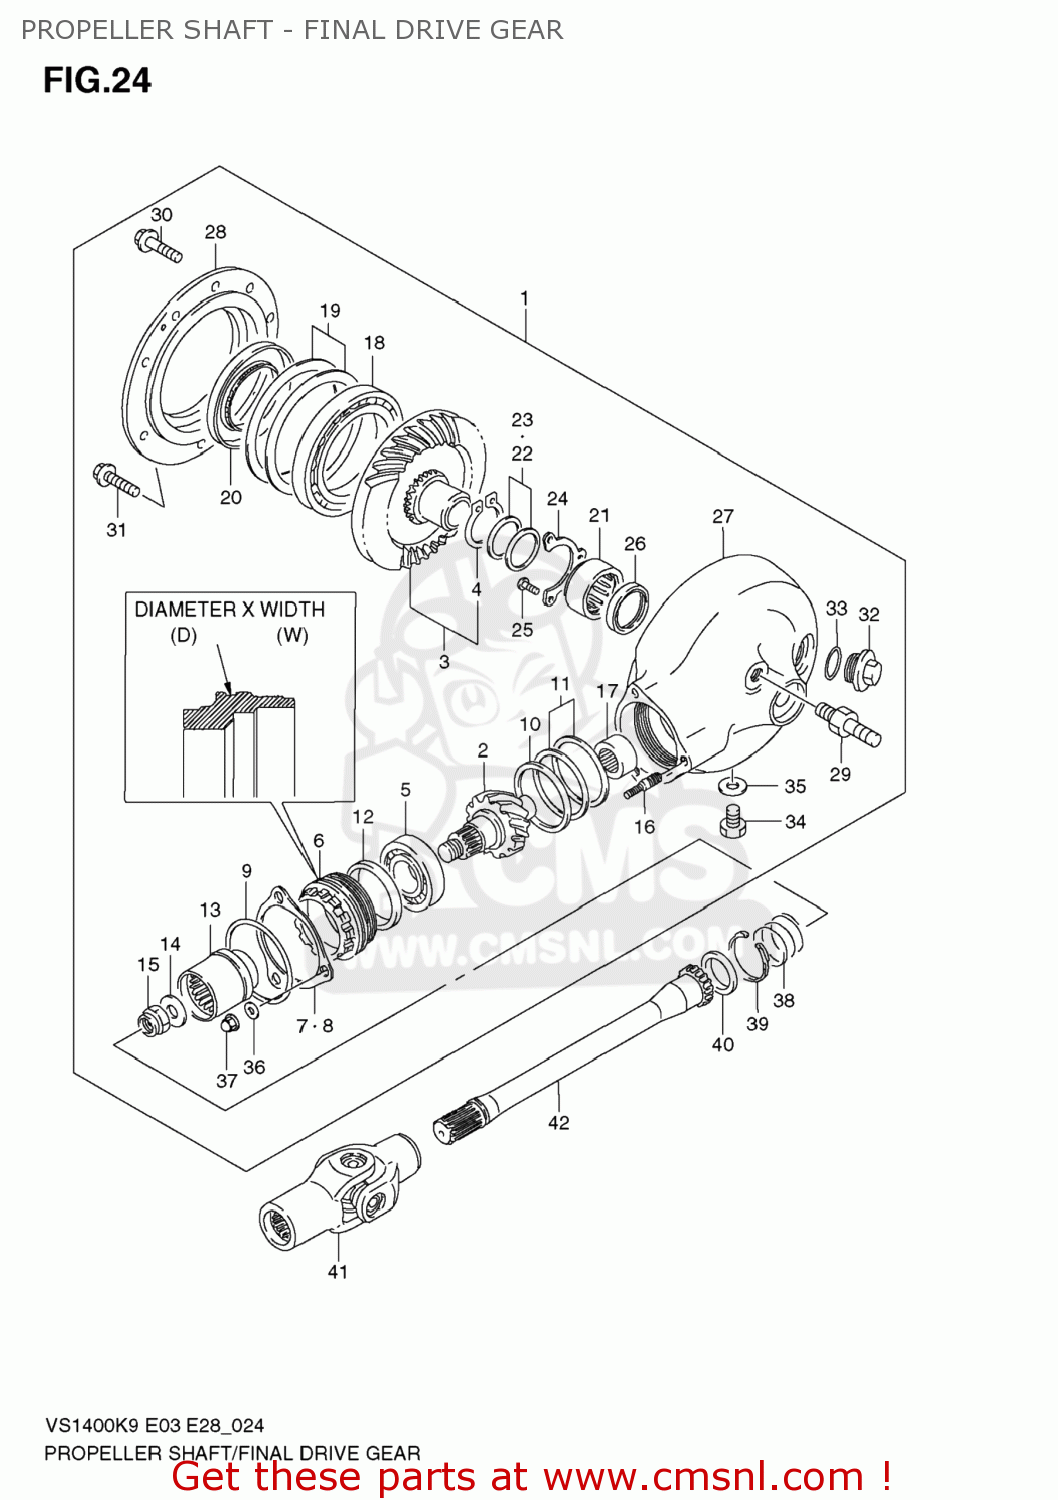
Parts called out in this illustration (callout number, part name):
1	GEAR & CASE SET,FINAL BEVEL
2	GEAR,FINAL DRIVE BEVEL
3	GEAR,FINAL DRIVEN BEVEL
4	.CIRCLIP
5	BEARING(28X68X18)
6	STOPPER,FINAL DRIVE BEARING
7	PLATE,BEARING STOPPER
8	PLATE,BEARING STOPPER
9	O RING(D:3.1,ID:63.9)
10	WASHER(54X68X1.5)
11	SHIM SET,FINAL DRIVE GEAR
12	SEAL,OIL
13	COUPLING,FINAL DRIVE GEAR
14	WASHER(16X29X4)
15	NUT
16	BOLT,STUD
17	BEARING(20X34X18)
18	BEARING(85X130X14)
19	SHIM SET,FINAL DRIVEN GEAR
20	SEAL,OIL(70X110X14.7)
21	BEARING(35X48X23.7)
22	WASHER(35X46X0.95)
23	SHIM SET,FINAL DRIVEN GEAR
24	RETAINER,FINAL DRIVEN GEAR BRG
25	BOLT(6X12)
26	SEAL,OIL(35X43X5)
27	CASE,FINAL GEAR
28	CASE,FINAL GEAR BEARING
29	BOLT,STUD
30	BOLT
31	BOLT
32	PLUG,30X9
33	O RING(D:3.1,ID:26.4)
34	PLUG(MAGNETO)
35	GASKET(13.8X18.8X4.8) (NAS)
36	WASHER
37	NUT
38	SPRING
39	CIRCLIP
40	SEAL,OIL(30X40.5X5.5)
41	YOKE COMP,UNIVERSAL JOINT
42	SHAFT,PROPELLER
